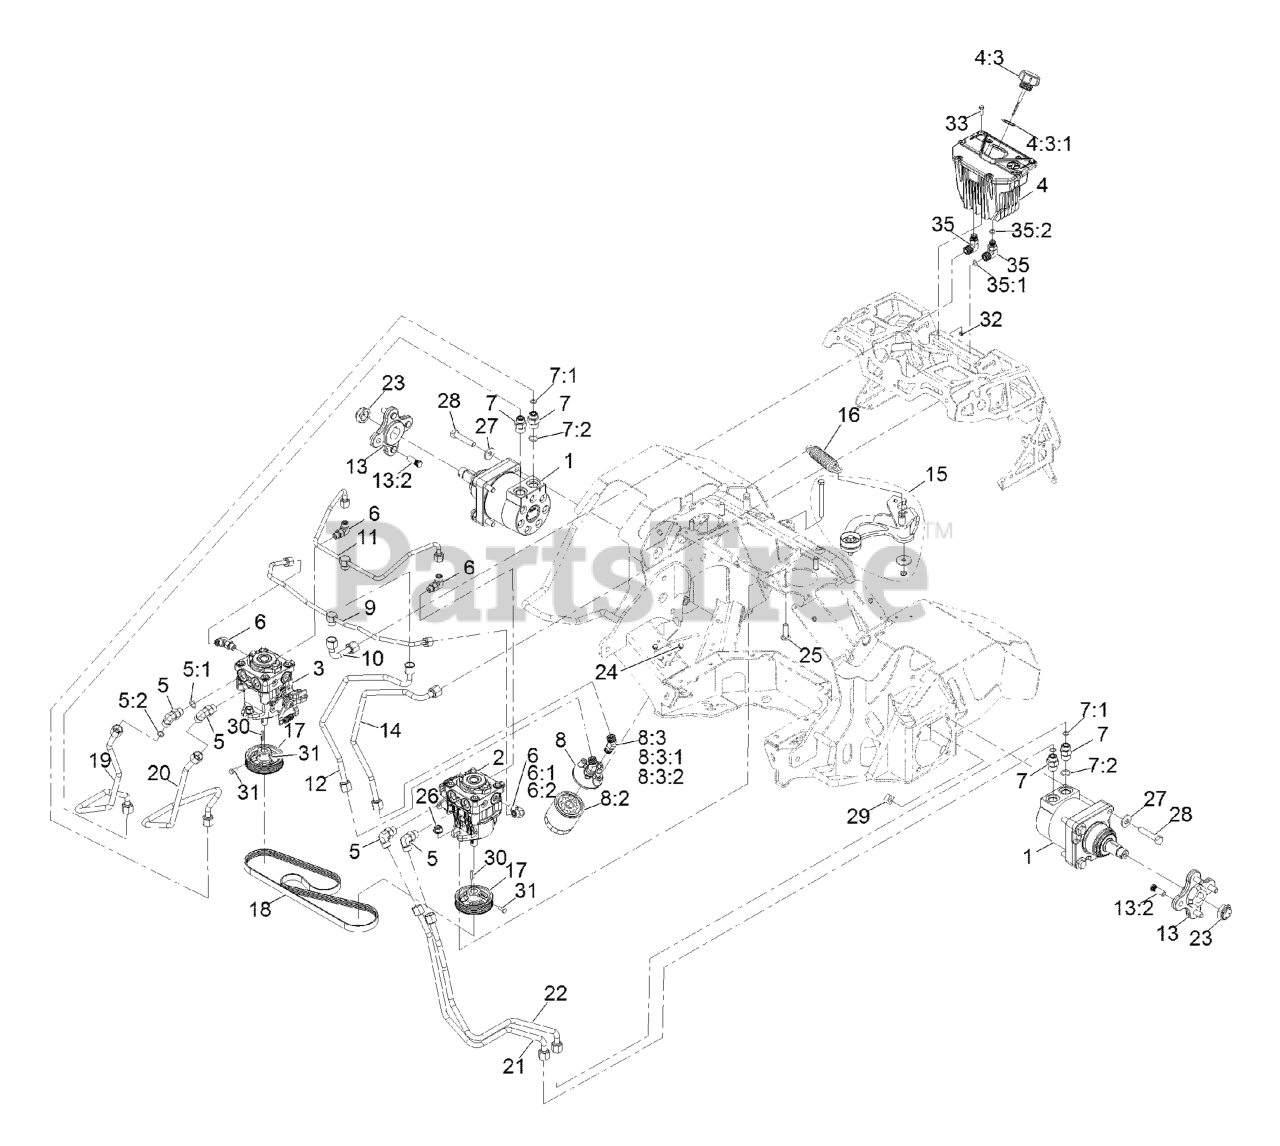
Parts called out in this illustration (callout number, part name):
1	Motor, Tl195
2	PUMP, 12CC
3	PUMP, 12CC
4	ASM, Hydraulic Reservoir
4:3	RESERVOIR CAP ASM
4:3:1	GASKET-CAP
5	FITTING-ELBOW, 90 DEG
5:1	O-RING
5:2	O-RING
6	FITTING-ELBOW, 90 DEG
6:1	O-RING
6:2	O-RING
7	FITTING-STRAIGHT
7:1	O-RING
7:2	O-RING
8	ASM, Filter Head
8:2	FILTER-25 MICRON, BI-DIRE
8:3	Adapter
8:3:1	O-RING
8:3:2	O-RING
9	Line, Hydraulic, Case Tee
10	Line, Hydraulic, Case
11	Line, Hydraulic, Charge Tee
12	Line, Hydraulic, Charge
13	ASM, Hub W/ Studs
13:2	STUD-WHEEL
14	Line, Hydraulic, Supply
15	ASM, Idler Arm
16	SPRING, EXTENSION
17	PULLEY, PUMP
18	Belt, Pvk5
19	Line, Hydraulic, B-A
20	Line, Hydraulic, A-B
21	Line, Hydraulic, B-B
22	Line, Hydraulic, A-A
23	LOCKNUT
24	SCREW-HWH
25	BOLT-CARR
26	NUT-HF, NI
27	WASHER-SPRING
28	SCREW-HH
29	NUT-SQUARE
31	SCREW-HH
32	NUT-LOCK, NI
33	SCREW-HWH
35	Fitting-HYD, 90 DEG
35:1	O-RING
35:2	O-RING
